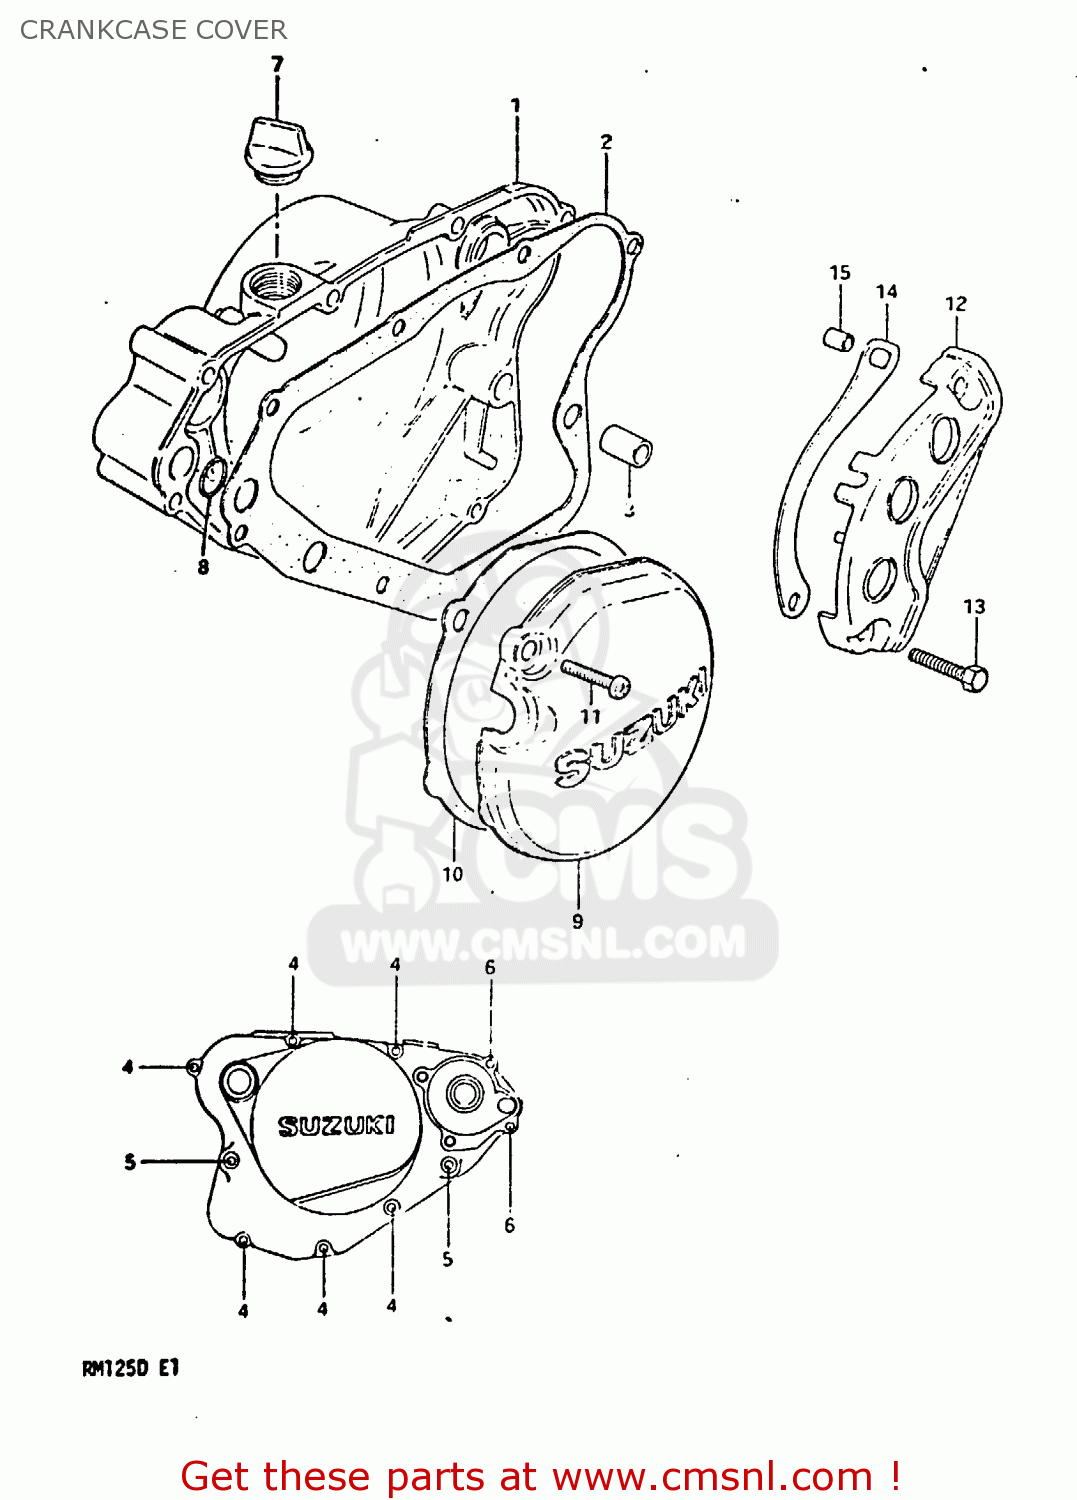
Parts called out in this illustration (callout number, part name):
1	COVER,CLUTCH
2	GASKET,CLUTCH COVER (MCA)
3	PIN
4	SCREW
5	SCREW (6X45)
6	SCREW 6X70
7	PLUG,OIL FILTER
8	O RING(D:1.9,ID:14.5)
9	COVER,MAGNETO
10	GASKET,MAGNETO COVER (NAS)
11	SCREW
12	COVER,ENGINE SPROCKET
13	BOLT
14	PLATE,CHAIN FRONT GUIDE
15	SPACER(6.5X10.5X12)
